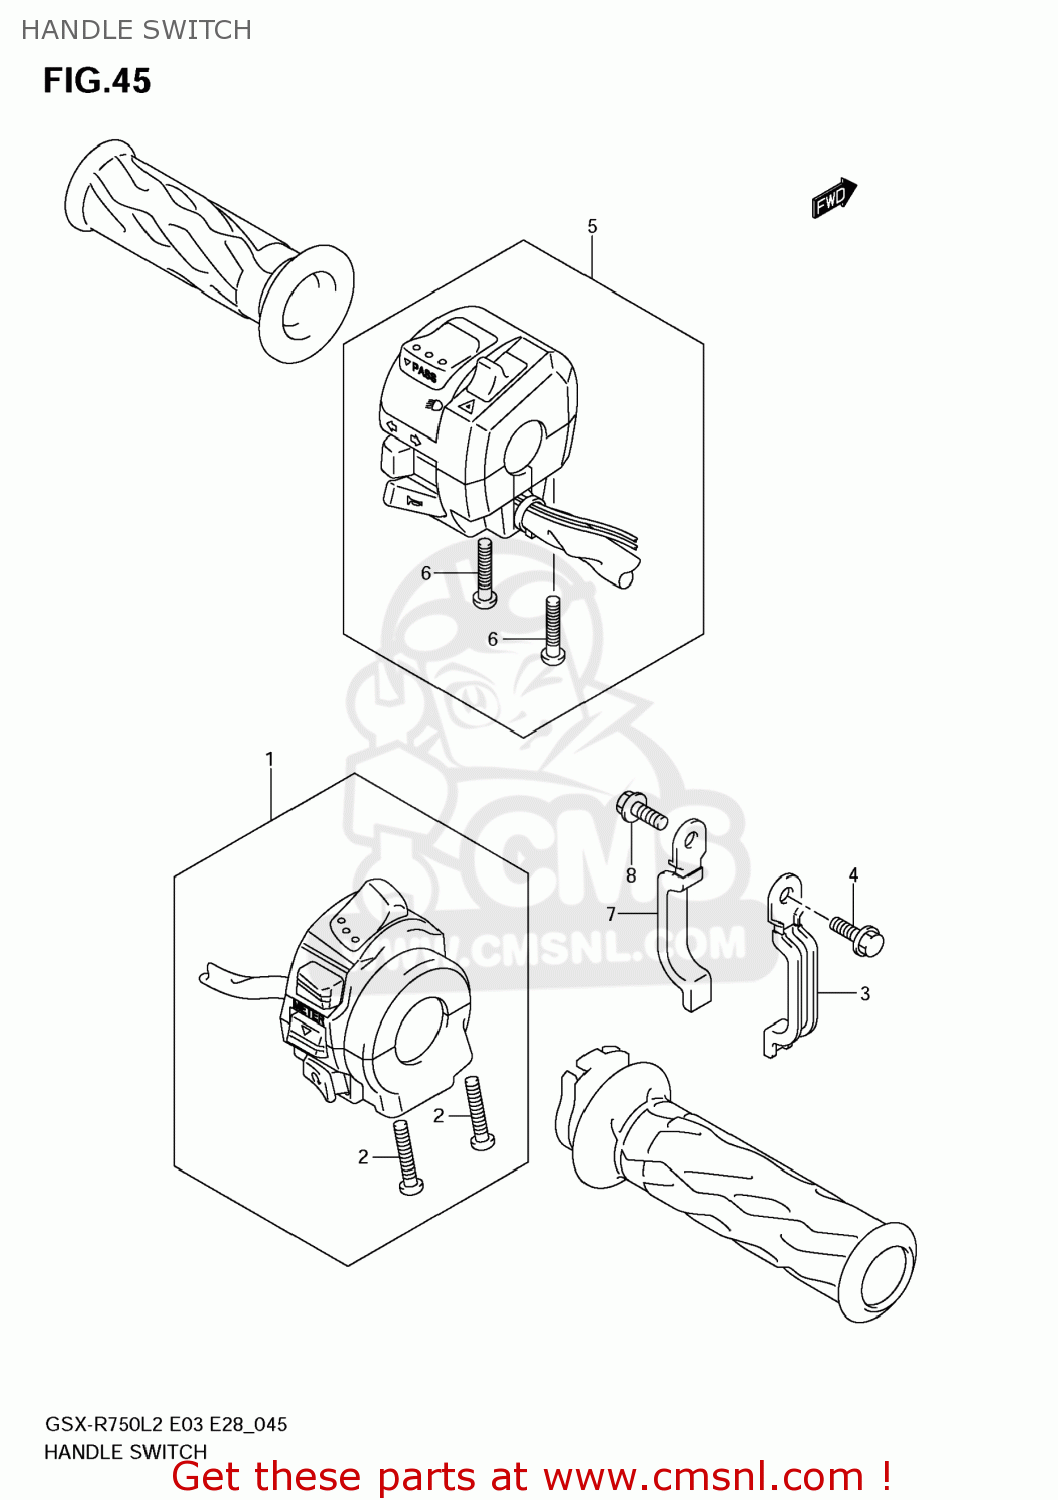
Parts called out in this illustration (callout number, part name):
1	SWITCH ASSY,HANDLE,R
2	SCREW
3	CLAMP
4	BOLT
5	SWITCH ASSY,HANDLE,L
6	SCREW
7	CLAMP
8	BOLT
